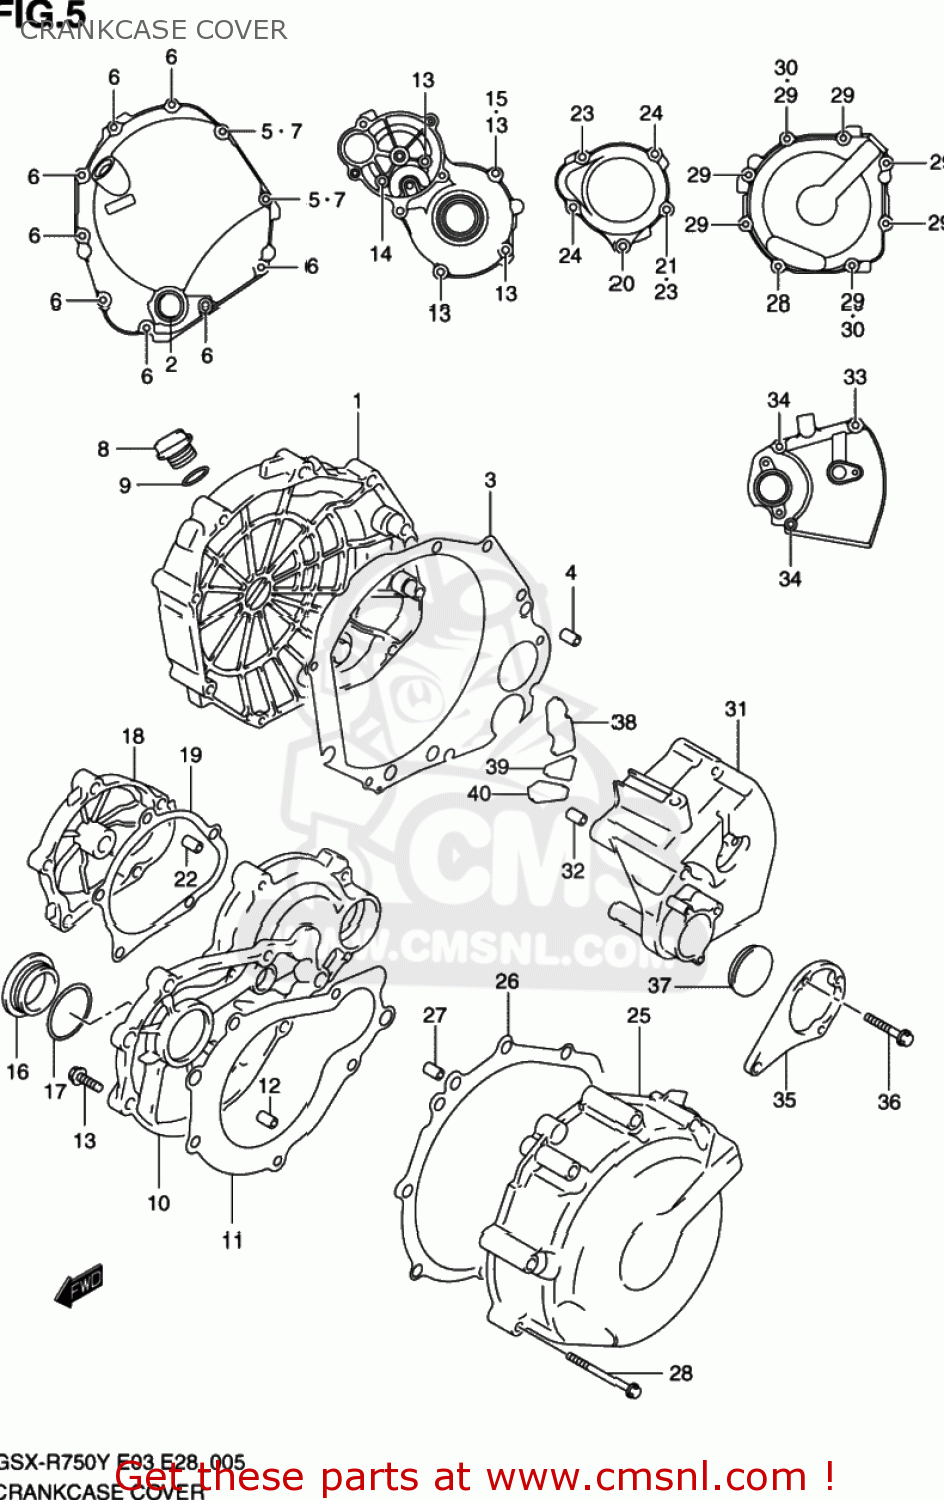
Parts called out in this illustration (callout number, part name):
1	COVER,CLUTCH
2	LENS,OIL LEVEL CHECK
3	GASKET,CL COVE (NAS)
4	PIN
5	GASKET(5.8X13X1.2) (NAS)
6	BOLT
7	BOLT
8	PLUG
9	O RING(D:3.1,ID:16.8)
10	COVER,STARTER CLUTCH
11	GASKET,STARTER CLUTCH COVER
12	PIN
13	BOLT,OIL PAN
14	BOLT
15	GASKET(5.8X13X1.2) (NAS)
16	PLUG
17	O RING(D:3.1,ID:32.7)
18	CAP,STARTER IDLE GEAR
19	GASKET,START IDLE GEAR CAP (NAS)
20	BOLT
21	GASKET(5.8X13X1.2) (NAS)
22	PIN
23	BOLT,OIL PAN
24	BOLT
25	COVER,MAGNETO
26	GASKET,MAGNETO COVER (NAS)
27	PIN
28	BOLT
30	GASKET(5.8X13X1.2) (NAS)
31	COVER,ENGINE SPROCKET
32	PIN
33	BOLT
34	BOLT
35	BRACKET,SPROCKET COVER
36	BOLT,OIL FILLE
37	CAP(OD:36)
38	DAMPER,SPROCKET COVER NO.1
39	DAMPER,SPROCKET COVER NO.2
40	DAMPER,SPROCKET COVER NO.3
